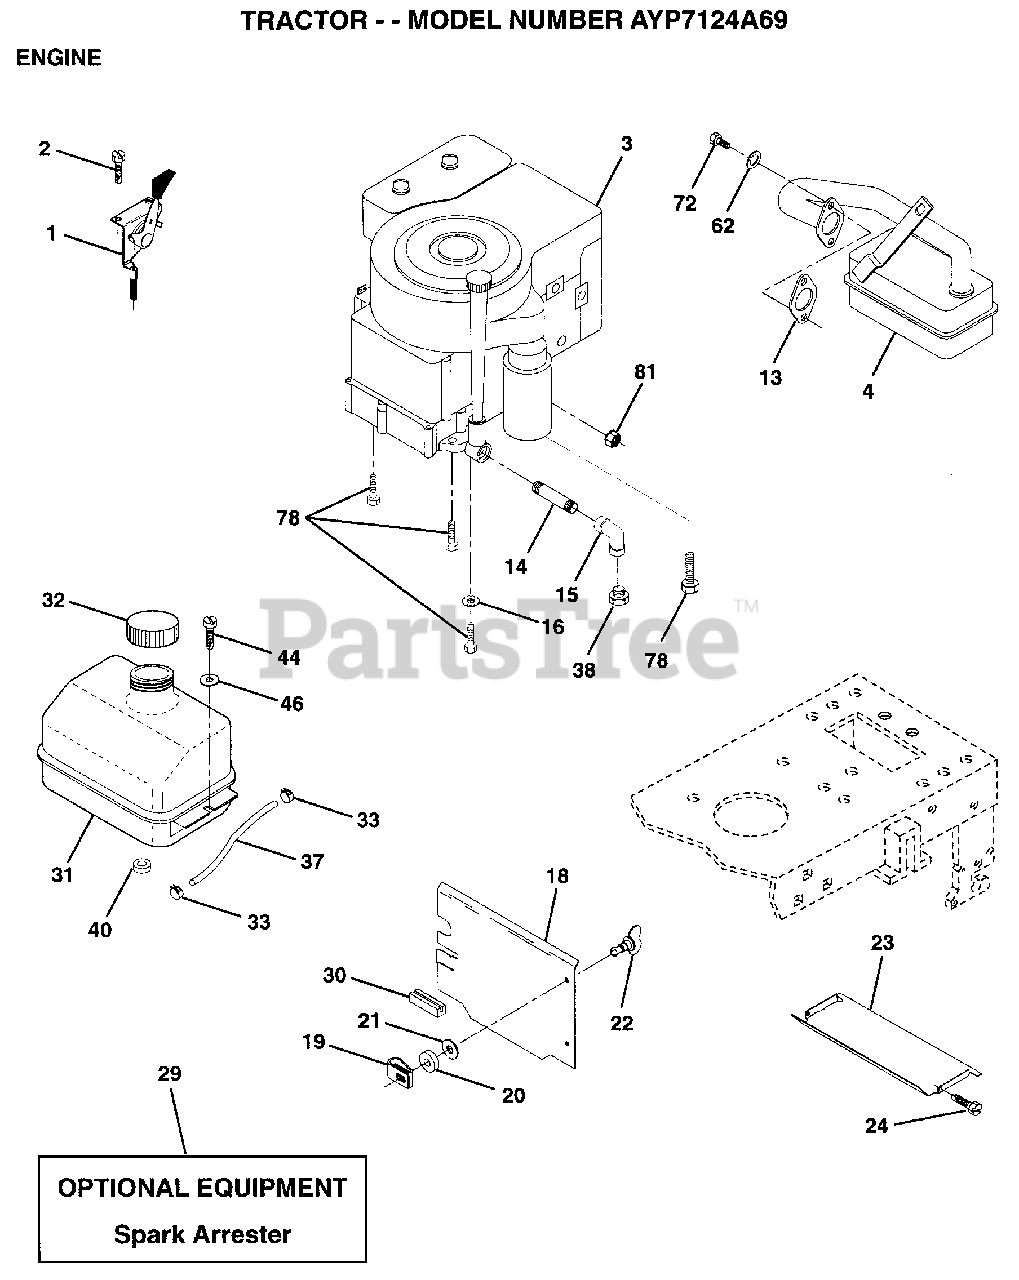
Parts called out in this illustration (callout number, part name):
1	CONTROL THROTTLE
2	SCREW LT
4	MUFFLER
13	GASKET ENG 1 313 LD TIN PLATED
14	PIPE NIPPLE
15	ELBOW
16	LOCKWASHER
18	SHIELD HEAT
19	RECEPTACLE LT
20	RETAINER LT
21	WASHER
22	STUD.1/4.TURN
23	HEAT SHIELD
24	SCREW
31	TANK.FUEL.LT.
32	CAP ASM FUEL
33	HOSE CLAMP
37	LINE FUEL
44	SCREW HEX CRT
46	WASHER
62	LOCKWASHER
72	SCREW
78	SCREW
81	NUT
